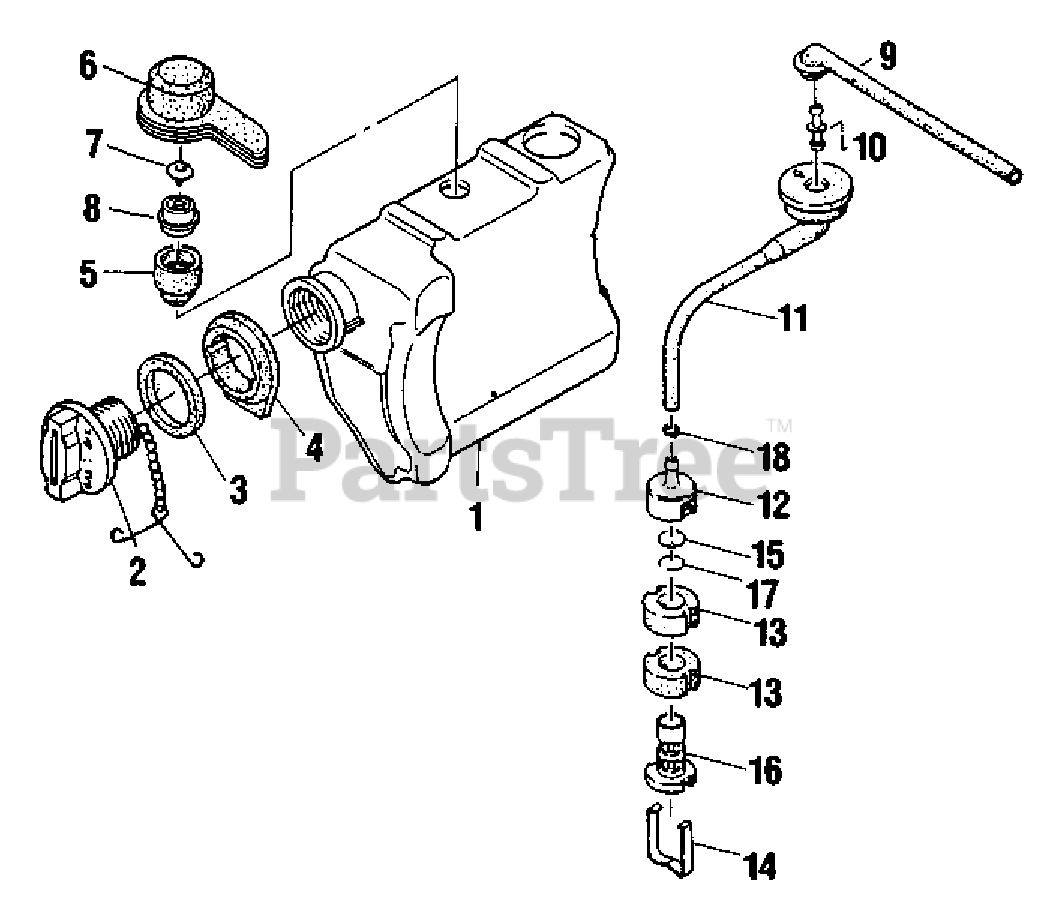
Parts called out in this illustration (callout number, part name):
1	FUEL TANK ASSY
2	CAP ASSY
3	GASKET, CAP
4	GASKET, FUEL CAP
5	HOLDER, VALVE
6	CAP, VENT
7	VENT ASSY
8	RETAINER
9	PIPE, FUEL
10	CONNECTOR, PIPE
11	PIPE, FUEL W/GROMMET
12	WEIGHT, FUEL LINE
13	FILTER, FUEL
14	CLIP, FILTER
16	BODY, FUEL FILTER
17	RING, RETAINING
18	CLIP Ø6
